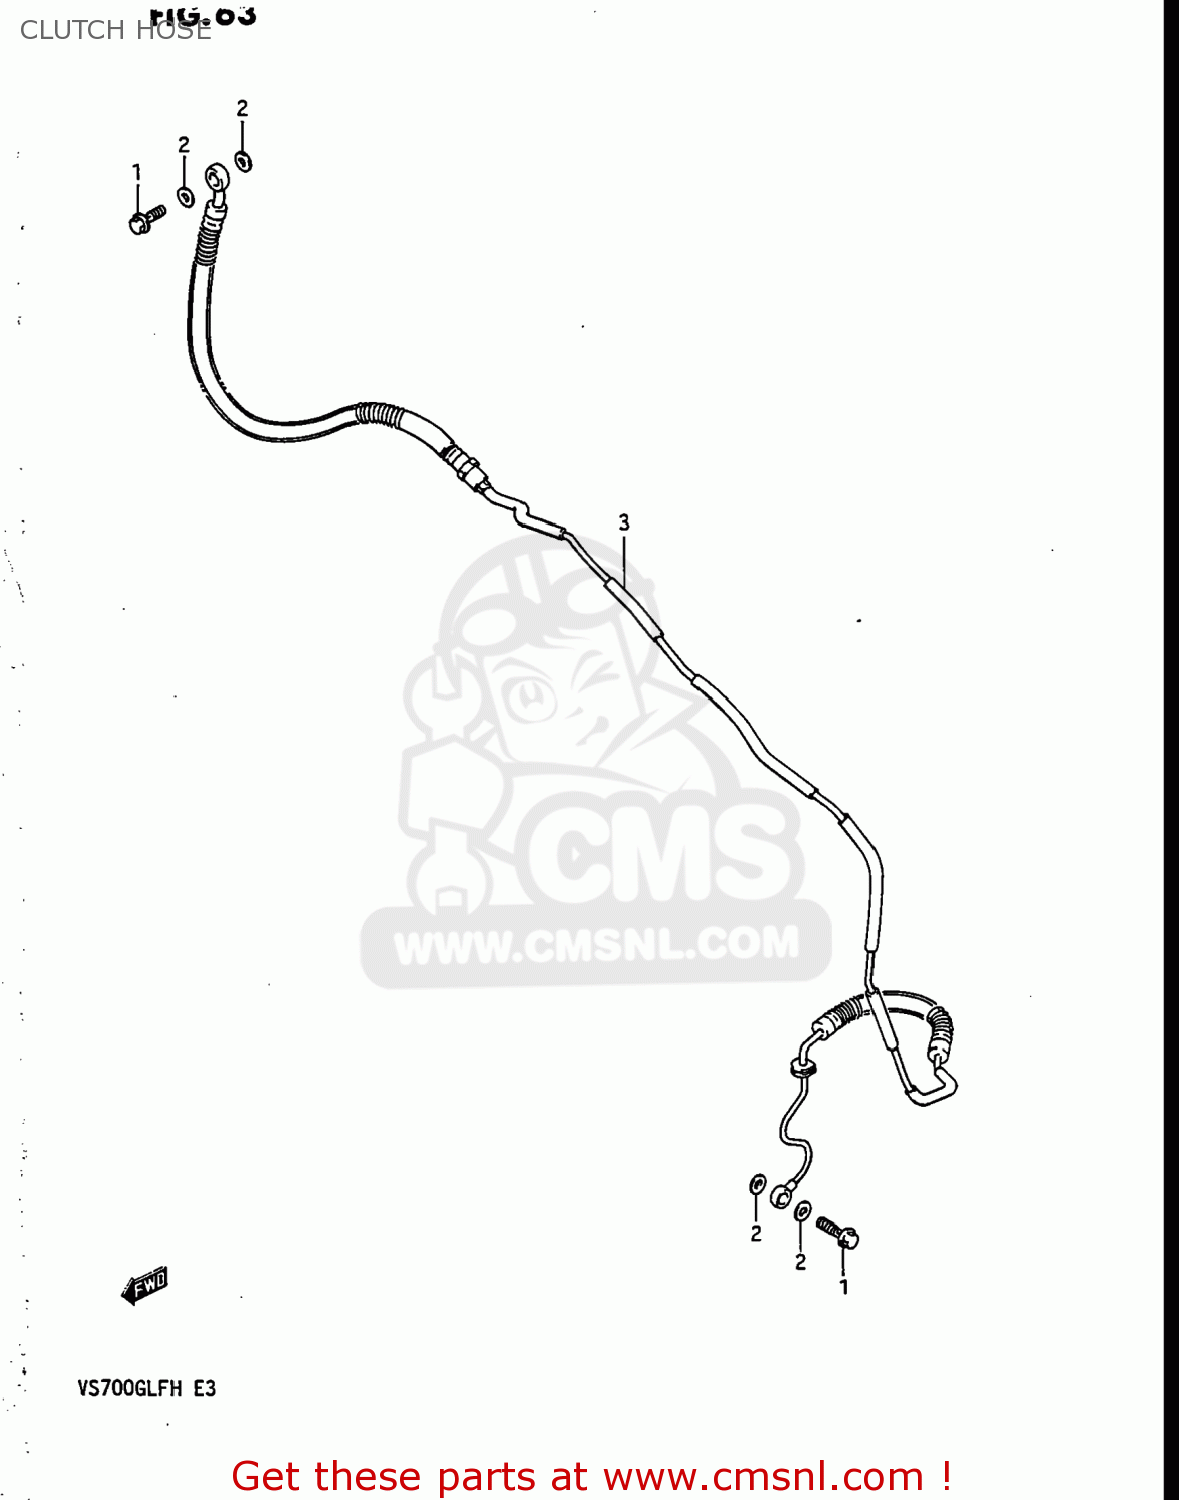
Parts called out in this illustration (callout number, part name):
1	BOLT UNION
2	WASHER(10X15X1.5)
3	HOSE ASSY,CLUTCH
